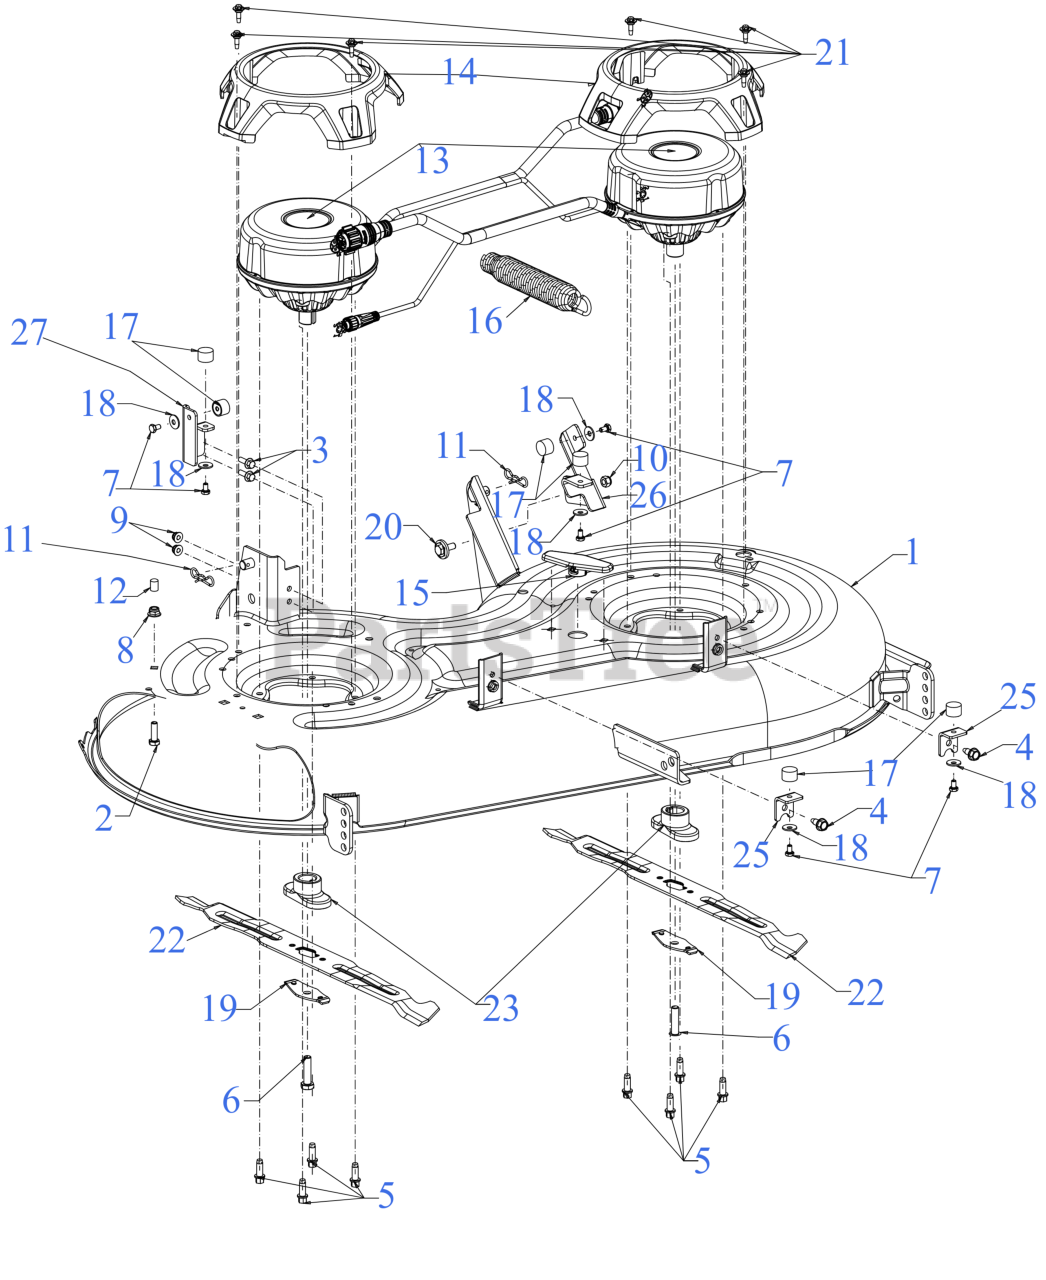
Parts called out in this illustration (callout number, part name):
1	42" DECK
2	SCREW 5/16-18 x 1.0 GR5
3	SCREW 1/4-20 x .75 GR5
4	SCREW M8-1.25 x .750
5	SCREW 5/16-18 x .875
6	SCREW 3/8-24 x 1.50 GR8
7	SCREW M6-1.0X10MM GR8.8
8	FLANGE LOCK NUT 5/16-18
9	FLANGE LOCK NUT
11	BOW TIE COTTER PIN
13	48V ELECTRIC DECK MOTOR
14	MOTOR COVER
16	LIFT ASSIST SPRING (SMALL)
18	SPRING WASHER BELL
19	BLADE BELL SUPPORT
20	SHOULDER SCREW
21	SHOULDER SCREW M6-1 .368 X.115
22	21.18" MULCH BLADE (S SHAPE CENTER HOLE)
22	Cub Cadet 42" BLADE SET
23	BLADE ADAPTER (#6 X 1.19 W/S)
25	UPSTOP BRACKET
26	UPSTOP BRACKET (LH)
27	UPSTOP BRACKET (RH)
